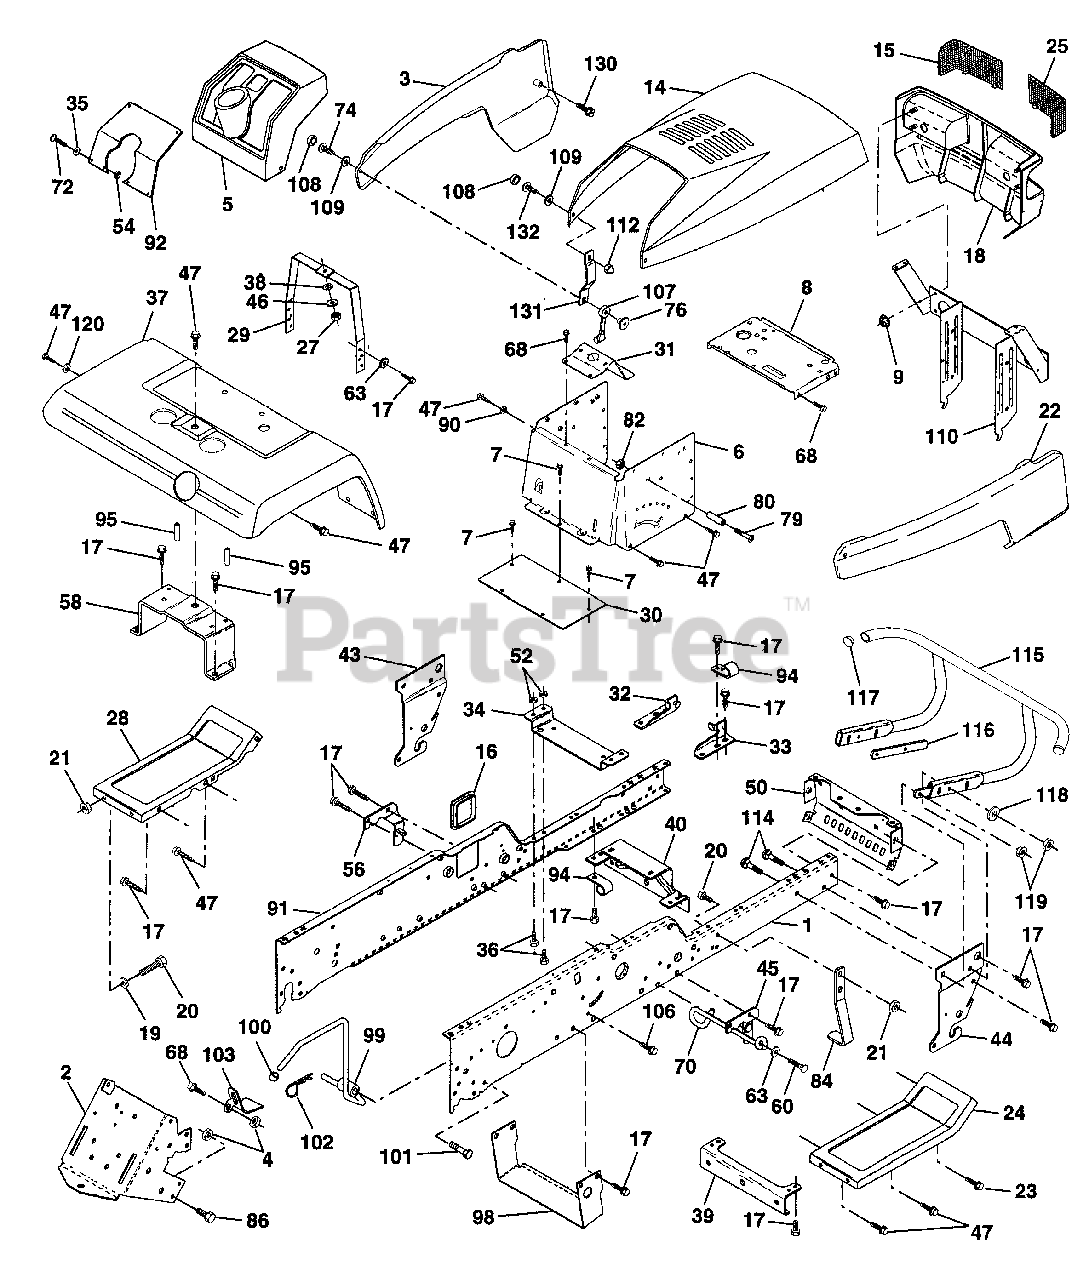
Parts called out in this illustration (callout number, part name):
1	Rail, Frame RH
2	Drawbar, Gt
3	Panel Asm., Side LH
4	Nut, Lock Hex 7/16 Unc
5	Dash, Plastic Black
6	Dash 1-PCS, Lower
7	Screw, Thd Cut 1/4-20 x 1/2
8	Support, Battery
14	Hood Asm., Pnt
15	Lens, Headlight LH
16	Cover, Access
17	Screw, Thdrol 3/8-16 x 3/4
19	Washer 13/32 x 13/16 x 12 Ga.
20	Bolt, Fin Hex 3/8-16 x 1
21	Nut, Crownlock 3/8-16 Unc
22	Panel Asm., Side RH
23	Screw Thdrol. 3/8-16 x 1 Ty-TT
24	Footrest, RH
25	Lens Headlight RH
27	Nut Fin Hex 1/4-20
28	Footrest, LH
29	Bracket, Support Dash
31	Brace, Support Steering
32	Bracket Asm., Frame Pivot Lh
33	Bracket Asm., Frame Pivot Rh
34	Bracket, Engine Support Rear
35	Washer 11/32 x 11/16 x 16 Ga.
36	Bolt, Fin Hex 5/16-18 x 3/4
37	Fender, Pnt.
38	Washer, Lock 1/4
39	Bracket, Axle Front
40	Bracket, Support Axle/Engine
43	Bracket, Spnsn Front Lh
44	Bracket, Spnsn Front Rh
45	Bracket Asm., Susp Chassis Rh
46	Washer 9/32 x 3/4 x 16 Ga.
47	Screw Thdrol 3/8-16 x 1/2
50	Bracket, Chassis Front
52	Locknut, Hex W/Ins 5/16-18 Unc
54	Nut 5/16-18
56	Bracket Asm., Susp Chassis Lh
58	Bracket Asm., Fender
60	Screw Thdrol 3/8-16 x 1-1 /4
63	Washer 13/32 x 1 x 14 Ga.
68	Screw, Thdrol 5/16-18 x 1/2
70	Guide, Belt Mid Span
72	Screw, Mach Trhd 5/16-18 x 3/4
74	Screw, Machine #10-24
76	Nut, Weld #10-24
79	Screw, Machine #10-24 x 1/4
80	Spacer, Split
82	Nut #10-24
84	Stop, Over Center 44" 20/23" T. 94
86	Bolt, Fin Hex 7/16-14 Unc x 1
90	Washer, Lock External Tooth 3/8
91	Rail, Frame Lh
92	Plate, Silkscreen Dash
94	Clip, Fuel Line
95	Push Nut, Nylon
98	Bracket Chassis Skid
99	Rod Asm. Bypass
100	Cap Brake Parking Red
101	Screw Thdrol. 3/8-16 x 1-3/4
102	Retainer Spring 1"
103	Bracket Lock Bypass
106	Screw Thdrol. Hex Hd Zinc Mur
107	Latch, Chute Blk
108	Cap, Snap Black
109	Cap, Washer Snap
110	Pivot Asm. Grille/Hood Husq. VGT
112	Nut, Acorn, Hex #10-24
114	Bolt, Carriage 3/8-16 x 1-1/4
115	Bumper Asm.
116	Bracket Extension Bumper
117	Plug Plastic
118	Washer 13/32 x 13/16 x 16 Ga.
119	Nut Crownlock 3/8-16 UNC
120	Washer 13/32 x 1 x 16 Ga.
130	Screw, SLTD Hex Hd. W/PI Washer
131	Bracket Support Hood/Panel YP
132	Screw Truss Hd, #10-24 x 3/8
